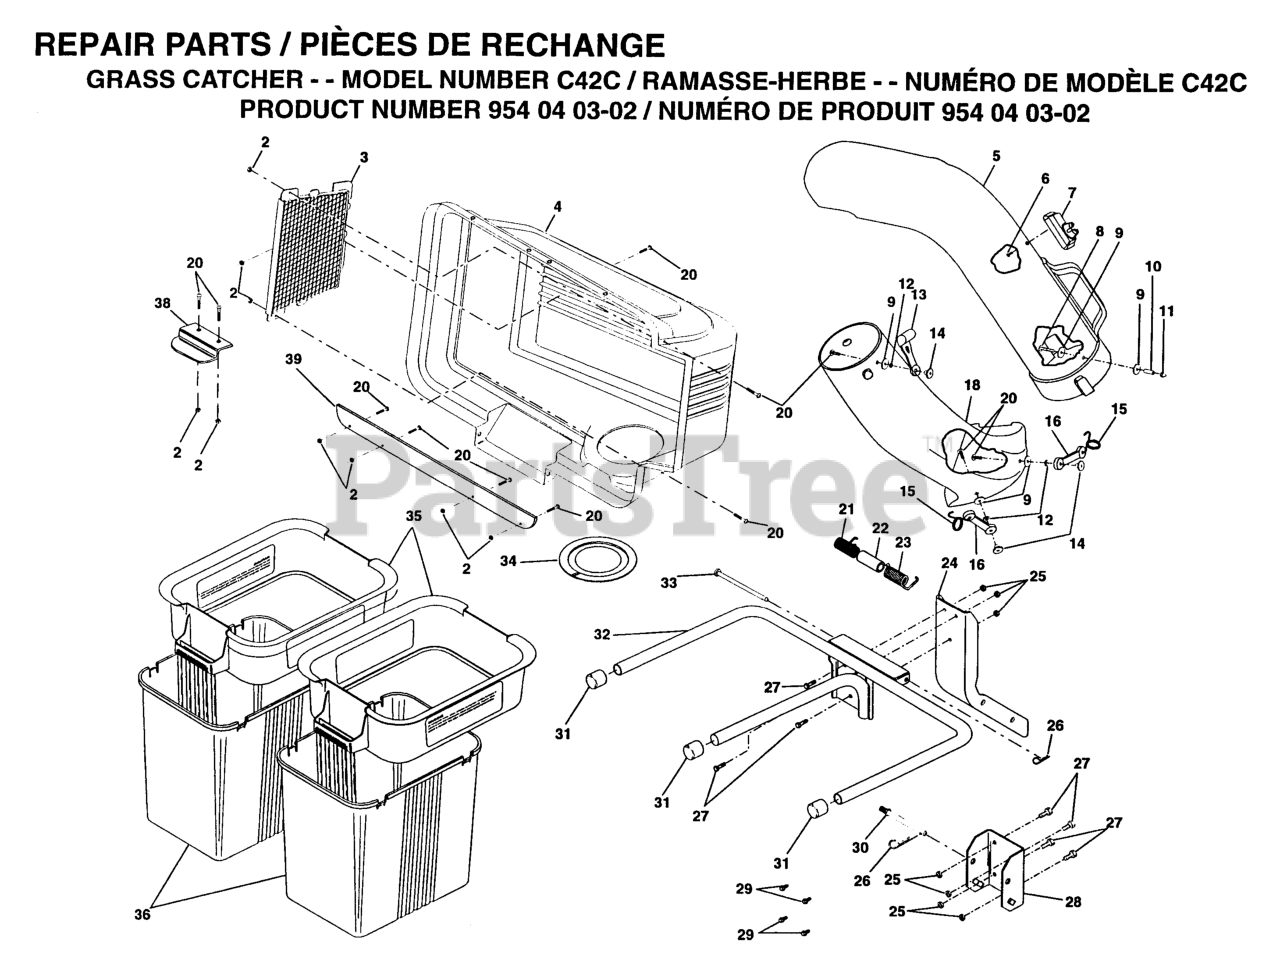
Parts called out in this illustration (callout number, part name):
2	Nut, Crownlock #10-24
3	COVER SCREEN
4	COVER
5	CHUTE.UPPER.42"
7	INDICATOR DUMP BAG
8	SCREW
11	NUT
12	LOCKWASHER #10
13	LATCH.HOOD.
14	WELDNUT
15	HOOK LATCH
16	RUBBER LATCH
18	LOWER CHUTE FOR 42" BAGGER
20	SCREW
21	SPRING COVER LH
22	SPACER.COVER.BAGGER
23	SPRING COVER RH
24	POST, SUPPORT
25	LOCKNUT
26	RETAINER-SPRNG RB
27	BOLT
28	MTG BRACKET
29	Screw 5/16-18 x 1/2 Hex, Self Tapping 5/16-18 x 1/2
30	SUPPORT POST PIN
31	TUBING PLUG
32	BAGGER FRAME
33	HINGE PIN
34	GASKET.COVER.BAGGER
35	CONTAINER TOP
36	CONTAINER BOTTOM
38	LATCH CER38
39	STRIP.REINFORCE.BAGGER.2BIN.BL
